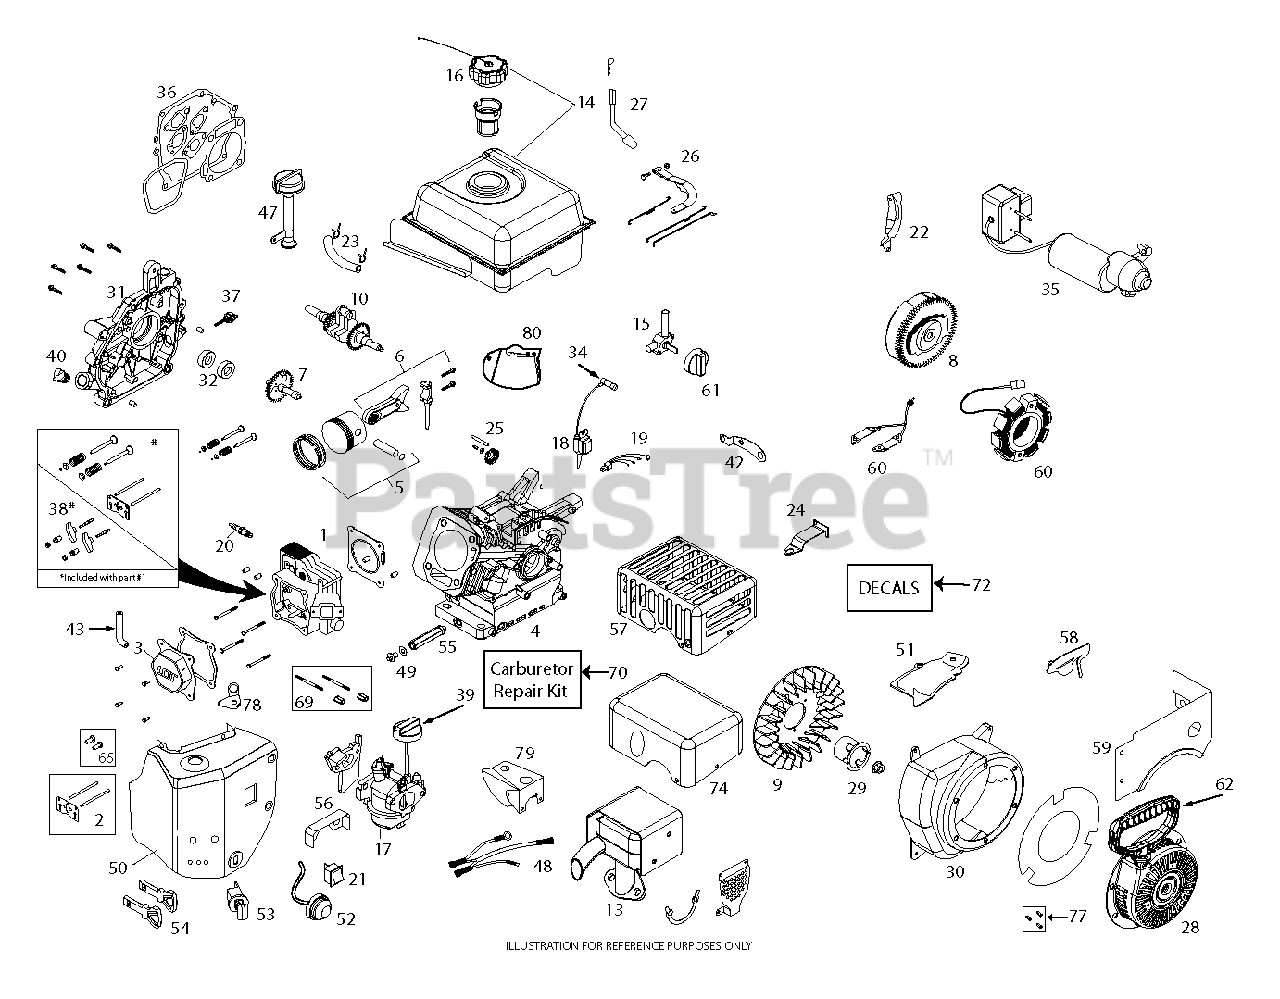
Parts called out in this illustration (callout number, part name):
1	CYLINDR.HEAD.SRV.KIT
2	KIT.PUSH.ROD.SRV(SK208-1001)
3	VALVE COVER ASSEMBLY
4	CYLINDER.ASM.SKSN0001.2
5	KIT.PISTON.SRV(SK208-1400)
6	KIT.CONNECT.ROD.SRV(SK208-1500
7	KIT.CAMSHAFT.SRV(SK208-1600)
8	208CC ELEC START FLYWHEEL
9	KIT.COOLNG.FAN.SERV(SK208-4000
13	ASSY.MUFFLER.GENII.SKSN0201.1
14	FUEL.TK.ASSY.GENII.SKSN0311.1
15	FUEL.PETCOCK.SNOW(SKSN4900)
16	FUEL CAP OVERSIZED CLICK STYLE
17	CARB.ASSY.GEN II,SKSN0312.1
18	208CC IGN COIL (STD)
20	SPARK.PLUG(2083810)
21	SWITCH.ON/OFF(SKSN-0403)
22	SHLD.ELEC.START.FLY(SKSN-0605)
23	FUEL HOSE KIT
24	SPEED.CTRL.BRKT.(SKSN0150)
25	GOVENOR.GEARS ASM(SK2082900)
26	CARBURETTOR GOVERNOR LINK.ASM.
27	KIT.GOVERNOR.CRANK(SK208-3100)
28	RECOIL.STRT.ROUND(BLK) SNOW
29	STRTER.CUP(NON-SLOT)SKSN0601.2
30	BLOWER HOUSING ASSEMBLY
30	BLOWER.HOUSING.ELEC.START.LCT
31	CRANKCASE COVER ASSY
31	COVER CRANKCASE.LCT.SK2083605
32	SEAL KIT (2 PCS)
34	SPARK.PLUG.BOOT.SNW,SKSN4691.1
35	ELEC.START.GEN2.SKSN0400.2
36	GASKET.KIT.208CC(SK2084300.1)
37	DIPSTICK SMALL
38	ROCKER ARM KIT
39	CHOKE.KNOW.SNOW(SKSN4500)
40	NON REMOVABLE PLUG
43	TUBE.BREATHER.LCT.208
47	High Oil Fill Tube Assembly
47	HIGH OIL FILL DIPSTICK ASSEM
48	WIRE.HARNESS.SNOW
49	KIT.OIL.DRAIN.PLUG(SK2089911
50	HEATER.BOX.ASY-GEN2
52	PRIMER.BULB.WITH HOSE (SNOW)
53	SWITH.KEY.ASSEM.SNOW.SINGLE.ST
54	KEY SET(2 KEYS) SKSN0407.1
55	EXTENDED OIL DRAIN TUBE
56	SHIELD.VAPOR.SNOW
57	CE COMPLAINT.MUFLR.SKSN0202.1
58	GOVERNOR.LINK.SHIELD PLATE
59	FUEL.TNK.SKRT.GENII.SKSN0103.1
60	208CC 60W ALTERNATOR
61	FUEL KNOB-SNOW
62	SNOW.STARTER.CHIP(SKSN-0603)
65	TAPPET.KIT.LCT.208CC
69	CARB.STUDS & COUPLING KIT.SNOW
70	Carburetor Repair Kit, LCT SK9900
74	Muffler Heat Shield Cover
77	Recoil Bolt Kit, LCT
